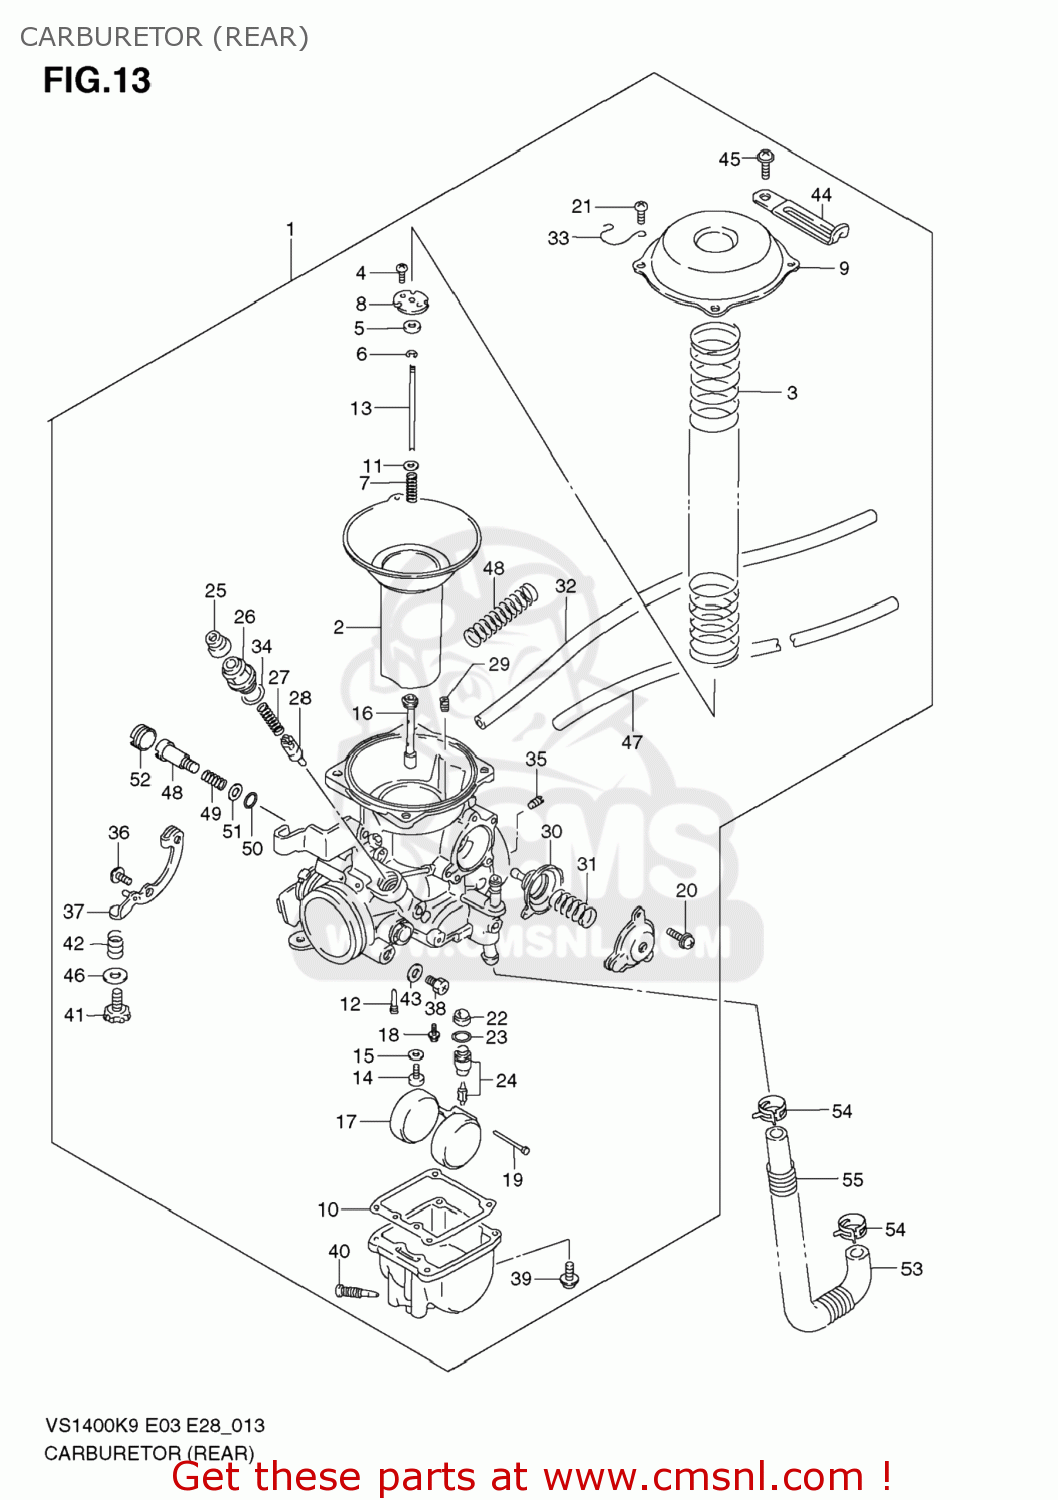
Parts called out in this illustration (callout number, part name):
1	CARBURETOR ASSY,FR
2	DIAPHRAGM,CARBURETOR
3	SPRING,DIAPHRAGM
4	SCREW
5	RING
6	CLIP
7	SPRING
8	PLATE
9	COVER
10	GASKET,FLOAT CHAMBER (NAS)
11	WASHER
12	JET,PILOT(55)
13	NEEDLE,JET
14	JET,MAIN(140)
15	WASHER
16	JET,NEEDLE(P-2M)
17	FLOAT
18	SCREW
19	PIN,FLOAT
20	SCREW
21	SCREW
22	FILTER
23	O RING,NEEDLE VALVE SEAT
24	VALVE ASSY,NEEDLE
25	CAP
26	HOLDER,GUIDE
27	SPRING
28	PLUNGER,STARTER
29	JET,AIR(1.55)
30	DIAPHRAGM ASSY
31	SPRING
32	HOSE(5X8.2X600)
33	CLIP
34	O RING
35	JET,PILOT(40)
36	SCREW
37	LEVER ASSY
38	SCREW
39	SCREW
40	SCREW,DRAIN
41	ADJUSTER
42	SPRING
43	WASHER
44	CLAMP(L:80)
45	SCREW
46	WASHER
47	HOSE ASSY
48	SCREW,PILOT
49	SPRING
50	O RING,PILOT AIR SCREW
51	WASHER
52	PLUG
53	HOSE,FUEL PUMP & CARB
54	CLIP
55	SPRING
